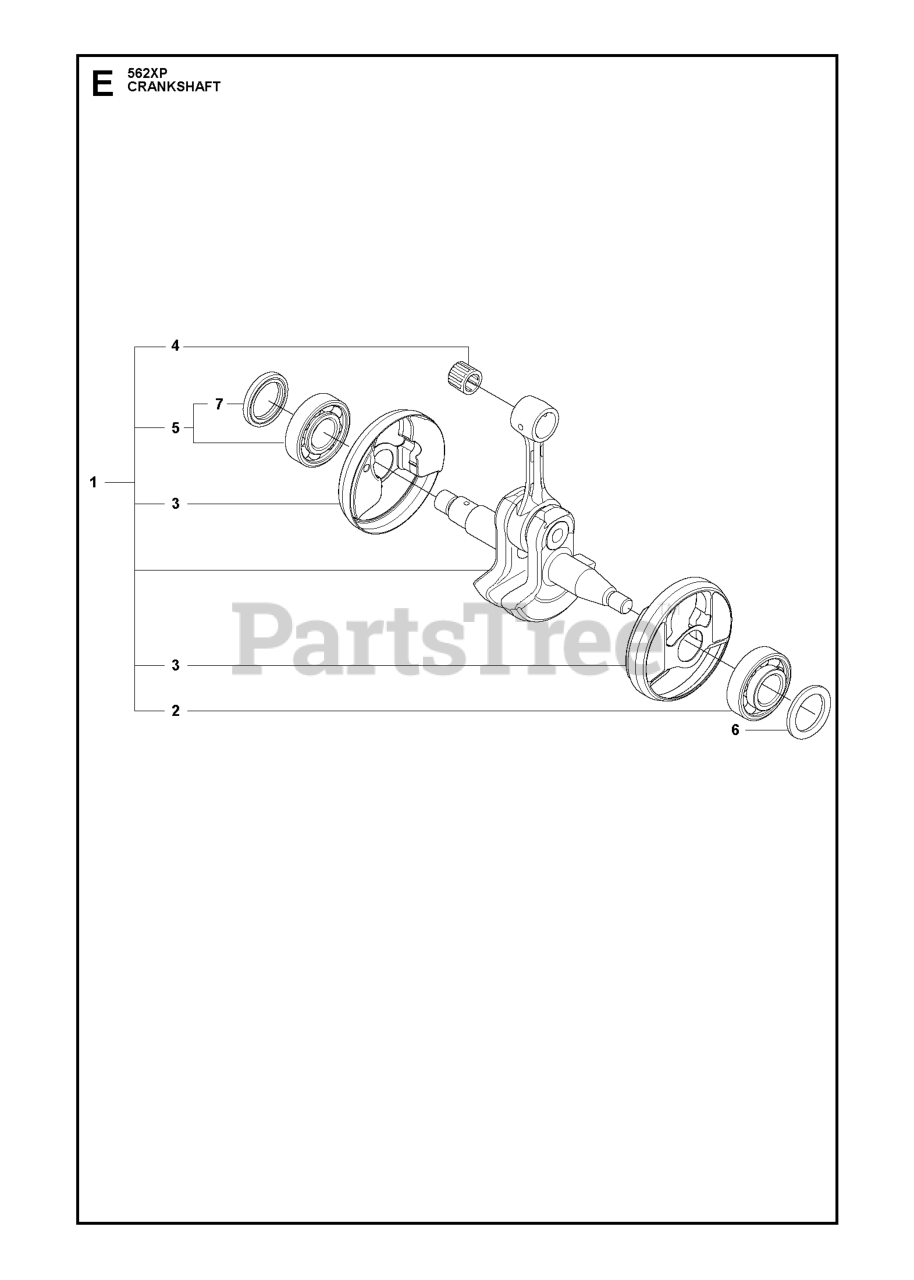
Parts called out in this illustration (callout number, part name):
1	CRANKSHAFT ASSY
2	BALL BEARING
4	SUPPORT BUSHING
5	BALL BEARING
6	RADIAL SEAL
7	RADIAL SEAL
